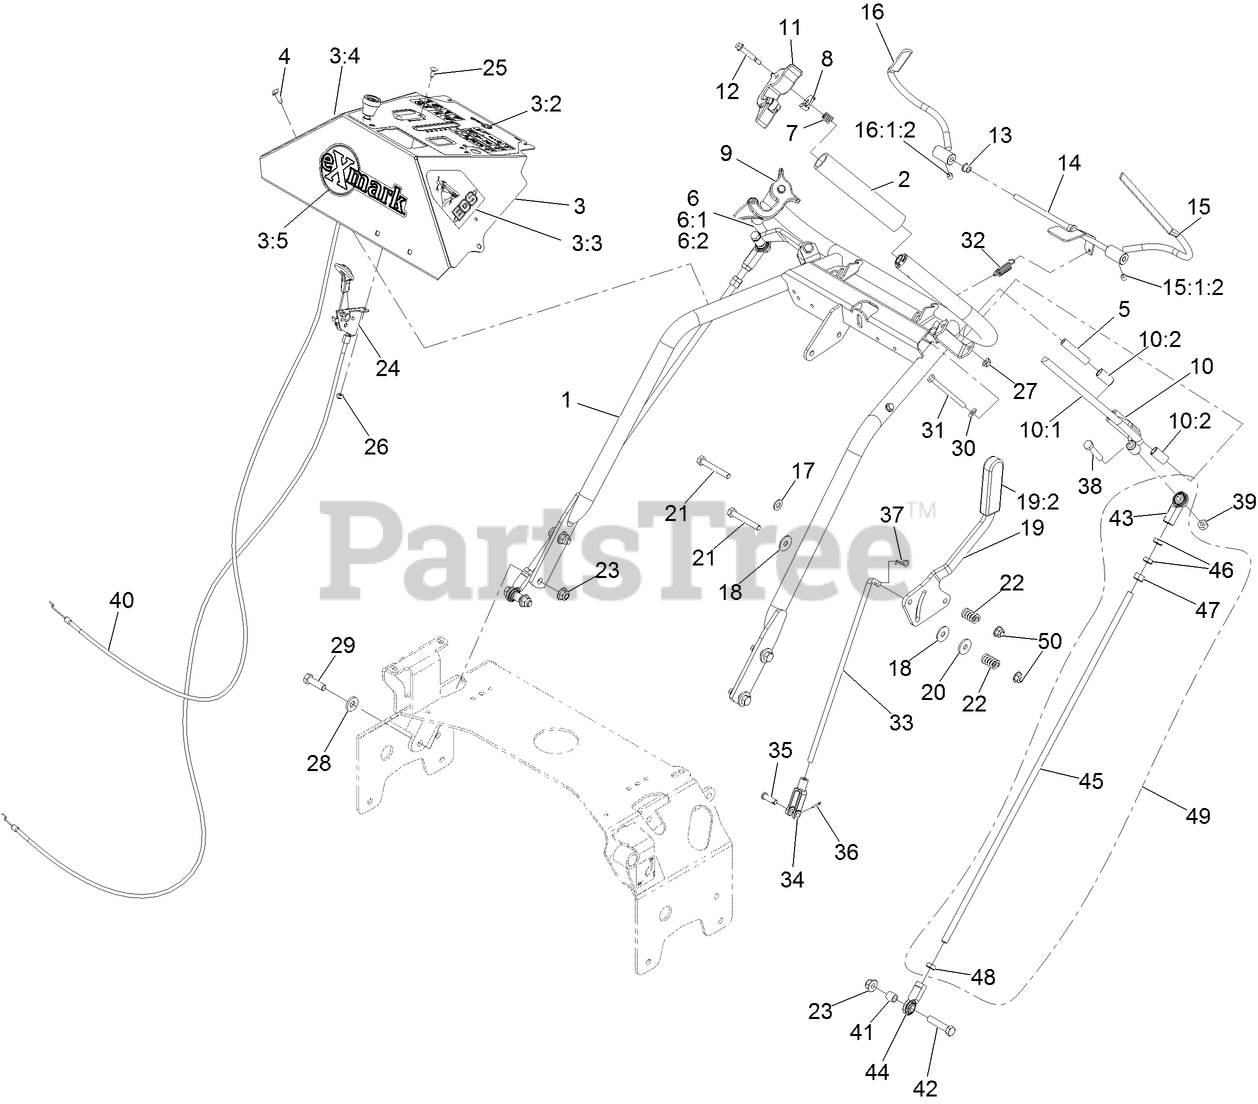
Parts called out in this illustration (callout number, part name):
1	WELD, HANDLE
2	GRIP-BAR, HANDLE
3	ASM, CONSOLE W/ DECALS
3:2	DECAL-CONSOLE
3:3	DECAL,LH ECS INSTRUCTION
3:4	DECAL,RH ECS INSTRUCTION
3:5	DECAL, EXMARK LOGO
4	SCREW-HWH
5	BUSHING-LEVER, DRIVE
6	DRIVE LEVER-ASM, RH
6:1	WLD,RH DRIVE LEVER
6:2	BUSHING, SLEEVE
7	SPRING-TANK, FUEL
8	LATCH, ECS
9	ASM,LATCH RH THUMB
10	DRIVE LEVER-ASM, LH
10:1	WLD,LH DRIVE LEVER
10:2	BUSHING, SLEEVE
11	ASM,LATCH LH THUMB
12	SCREW-SHOULDER
13	BUSHING-NYLON
14	WLD,OPC LEVER AXLE
15	WLD,LH OPC LEVER
15:1:2	SCREW-SET
16	WLD,RH OPC LEVER
16:1:2	SCREW-SET
17	WASHER-PLAIN
18	WASHER-FRICTION
19	LEVER, SHIFT W/GRIP
19:2	GRIP-HANDLE, STEERING
20	WASHER-FRICTION
21	SCREW-HH
22	SPRING-COMPRESSION
23	NUT-HF, NI
24	CONTROL-THROTTLE
25	BOLT-CARR
26	NUT-LOCK, NI
28	WASHER-BELLEVILLE
29	SCREW-HH
30	WASHER-FLAT
31	SCREW-HH
32	SPRING-EXTENSION
33	ROD,SPEED CONTROL
34	YOKE-ADJUSTABLE
35	PIN-CLEVIS
36	PIN-COTTER
37	PIN-COTTER
38	SCREW-HH
39	NUT-LOCK, NI
40	CABLE, CHOKE
41	SPACER-TUBE, PUMP LINK
42	SCREW-HH
43	JOINT-BALL, END
44	JOINT-BALL END, LH
45	LINK,DRIVE (PLTD)
46	NUT-HJ
47	NUT-HEX
48	NUT-HEX JAM, LH
49	DRIVE LINK ASM
50	NUT-HF, NI
